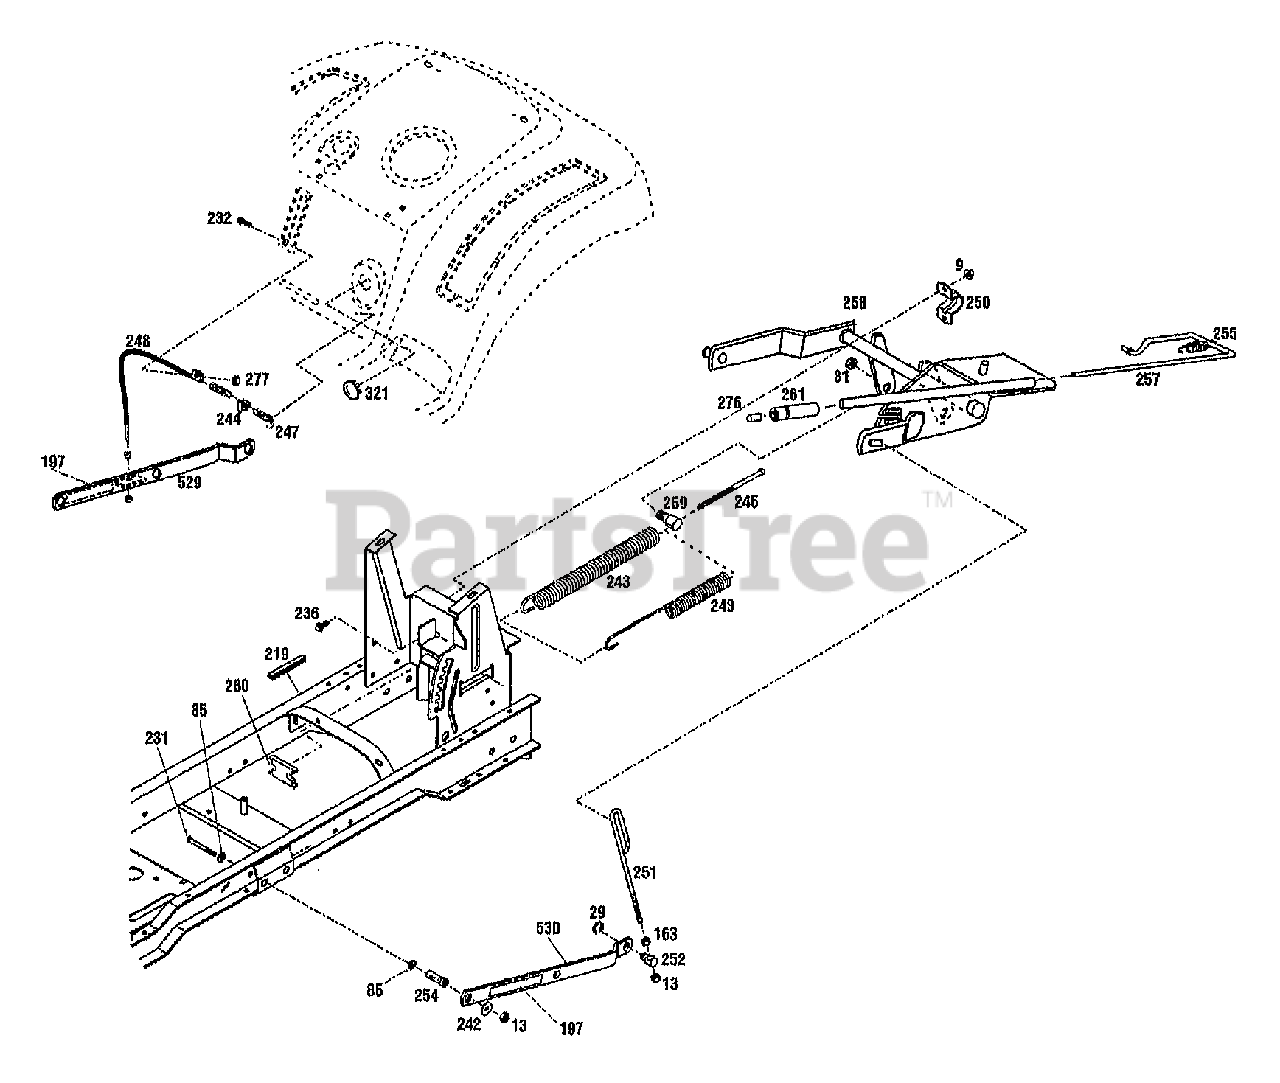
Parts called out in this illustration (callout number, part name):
9	NUT-HFLK 5/16-18 ZP
13	NUT-LOCK 3/8-16
29	RING-RETAINING
31	NUT-H/LK 5/8-11
85	WASHER-FLAT 3/8 SAE
163	NUT-HEX 3/8-16 ZP
197	DECAL-WARNING
231	SCR-HH 3/8-16X3.0 G5 ZP
232	SCR 10-24 X 5/8
236	SCR-HFLK 5/16-18X.75 ZP
242	WASHER-1.5X.375X.18 ZP
243	SPRING-LIFT ASSIST {13103}
243	SPRING-LIFT ASSIST {13104}
244	INDICATOR-HEIGHT
245	SCR-HH 3/8-16X5
247	SPRING-EXTENSION
248	ASSM-CABLE
250	CLAMP-LIFT
251	ROD-LIFT
252	SWIVEL-REAR LIFT
254	SPACER
255	SPRING-EXTENSION
258	ASSM-LIFT
259	BLOCK-PIVOT
260	SPRING-ANCHOR
261	GRIP-LIFT
276	BUTTON-LIFT
277	NUT-KEPS 10-24
321	PLUG-DOME
529	ASSM-RT LIFT LINK
530	ASSM-LT LIFT LINK
